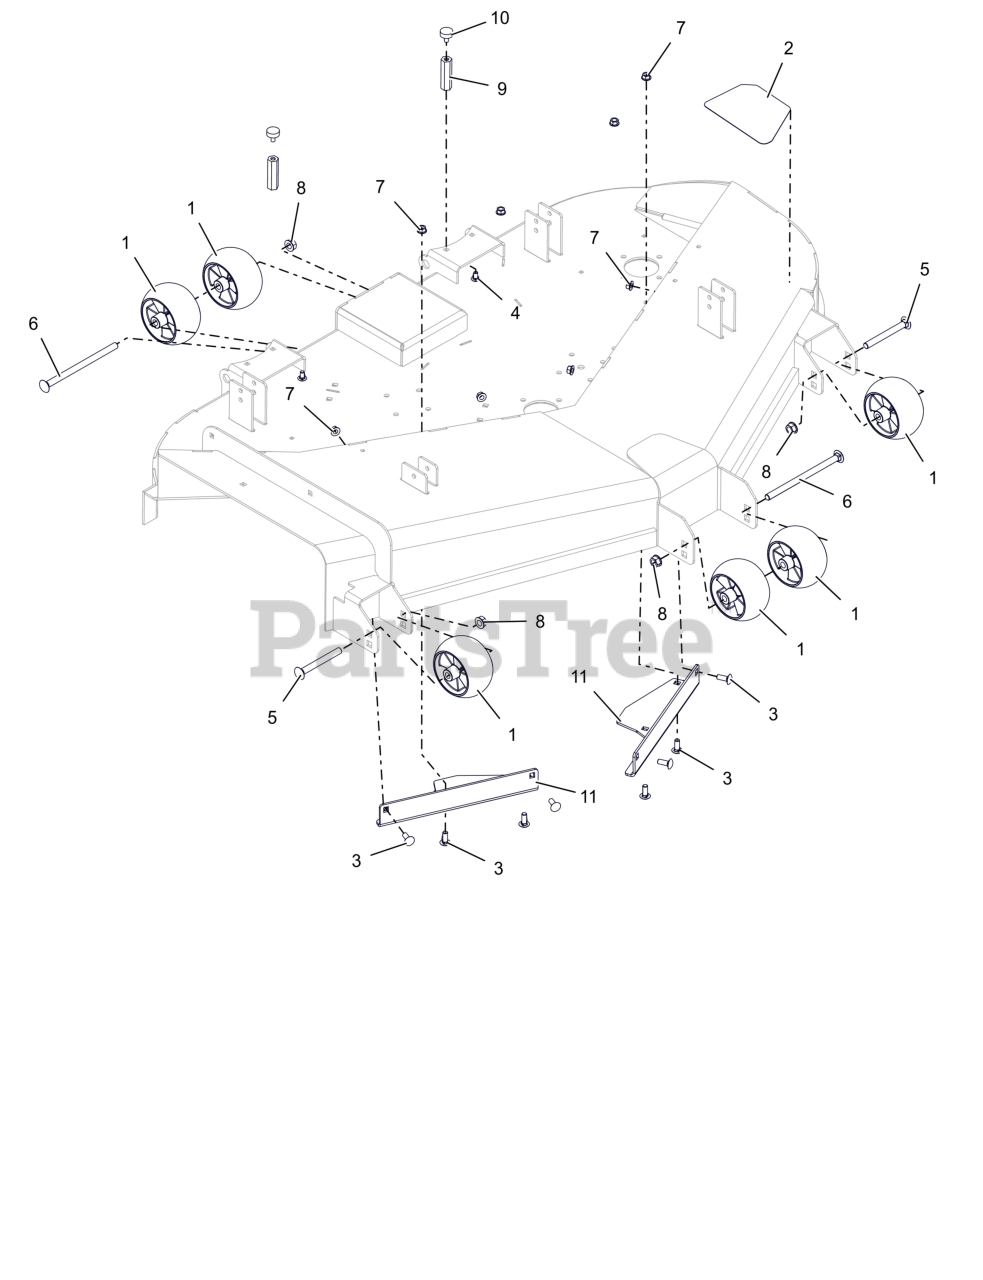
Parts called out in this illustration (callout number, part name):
1	WHEEL, ANTI SCALP - 5X3 CTR W/RIBS
2	GRIP, STEP ANTI SKID
3	BLT,RHSSN .38-16X1.00 G5 ZCC
4	BTL,RHSSN .313-18 X 0.625 G5 ZCC
5	BLT,RHNS .50-13X4.50 G5 ZCC NS
6	BLT,RHSN .50-13X8.00 G5 ZCC NS
7	NUT-LK-CTR-FLG .375-16 GF ZCC
8	NUT-LK-CTR-FLG .500-13 GG ZCC
9	NUT, COUPLING .31-18 2.75 LG
10	BUMPER, RUBBER
11	PLATE, WEAR (RED)
